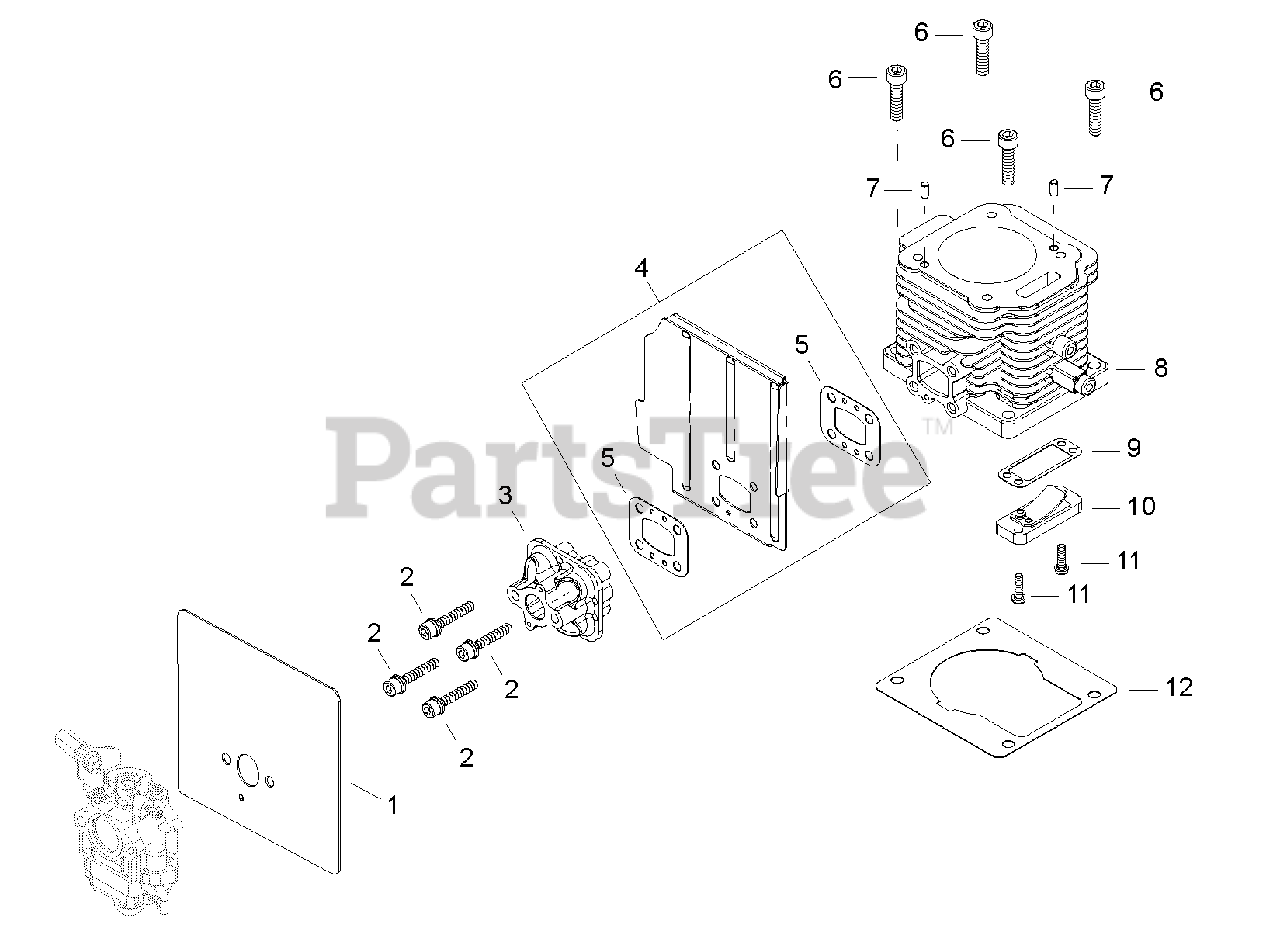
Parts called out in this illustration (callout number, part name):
1	GASKET, CARBURETOR
2	BOLT SS M5×30
3	INSULATOR, INTAKE
4	SHIELD ASSY, INTAKE HEAT
5	GASKET, INTAKE
6	BOLT 6×25
7	PIN, LOCATING Ø4×8
8	CYLINDER
9	GASKET, REED VALVE
10	VALVE ASSY, REED
11	SCREW M4×14
12	GASKET, CYLINDER
